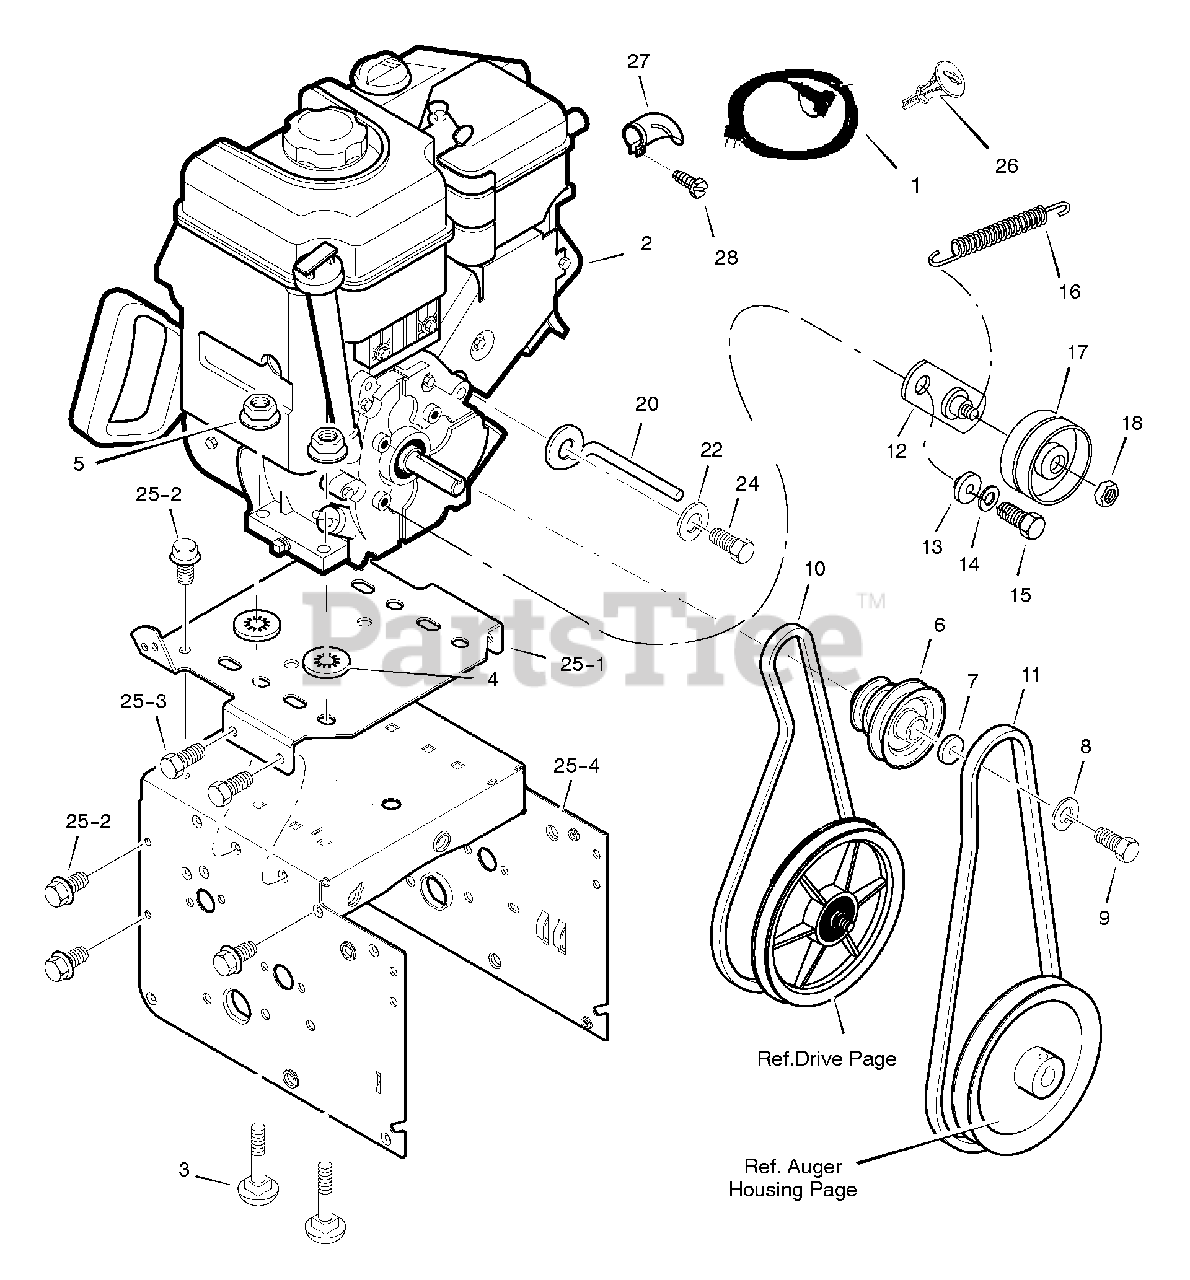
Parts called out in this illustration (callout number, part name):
1	CORD, STARTER
2	ENGINE
3	BOLT, CARRIAGE
4	RETAINER, PUSH
5	NUT
6	PULLEY, ENGINE
8	WASHER
10	BELT, DRIVE V 4L
11	BELT, AUGER V 3L
12	BRACKET ASSEMBLY, IDLER
13	BUSHING, IDLER BRACKET
14	WASHER, SPLIT
15	SCREW 5/16-24 X .75
16	SPRING, IDLER TRACTION DRIVE
17	PULLEY, IDLER
18	NUT, JAM 3/8-16
20	GUIDE, ROD BELT
22	WASHER
24	SCREW
25	FRAME ASSEMBLY
25-1	PLATE, ENGINE
25-2	SCREW
25-3	SCREW
25-4	MOTOR BOX
26	KEY, BRIGGS ENGINE
27	DEFLECTOR, MUFFLER
